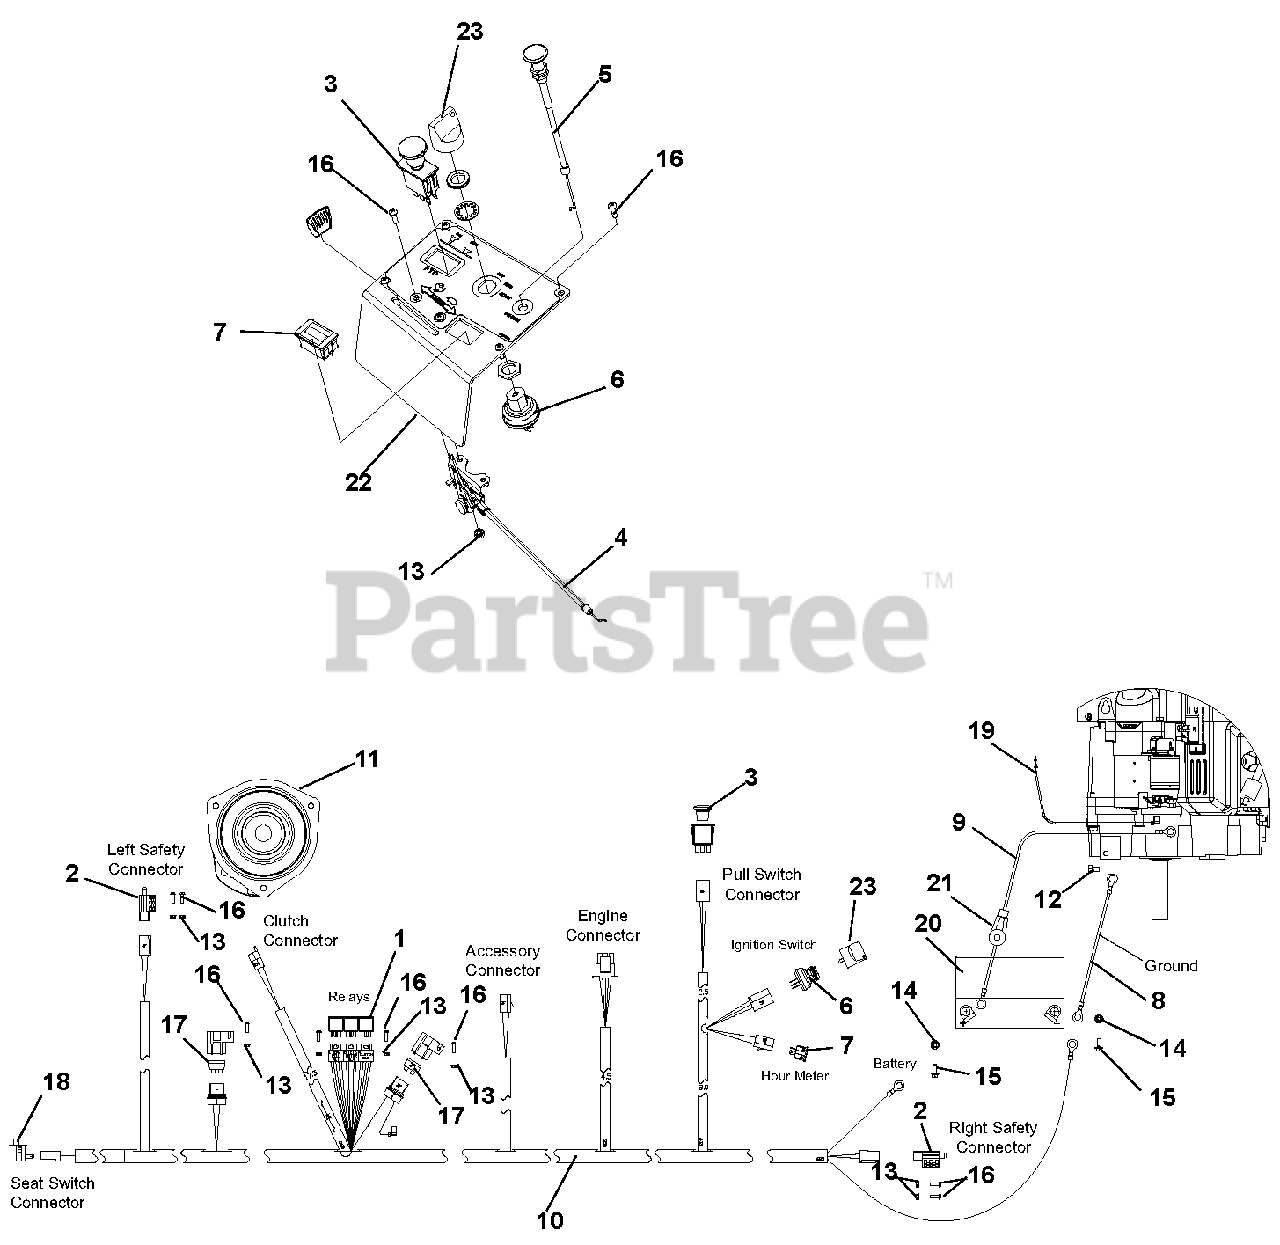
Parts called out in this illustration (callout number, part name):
1	Relay, ISO Mini Electric
2	Switch, Plunger
3	Switch, PTO Engagement
4	Cable, Throttle
5	Cable, Choke 48"
6	Switch, Ignition (Includes item 23)
7	Meter, Hour-LCD ALT
8	Cable, Battery - 25" Ground
9	Cable, Battery - 42" Positive
10	Harness, Wiring
11	Clutch, Electric - OGURA, GT3
12	Bolt, M8 x 1.25 x14 Hex 8.8
13	Locknut, 10-24 KEPS
14	Locknut, 1/4-20 WHIZ
15	Bolt, 1/4-20 x .625 WSH
16	Screw, Pan Head Phillips #10-24 x 5/8
17	Fuse, 20 AMP Blade S/O
18	Seat Switch
19	Lead, Starter Solenoid
20	Battery, 12V
21	Battery Terminal Boot, Red
22	Control Panel
23	Key, w/Shield
